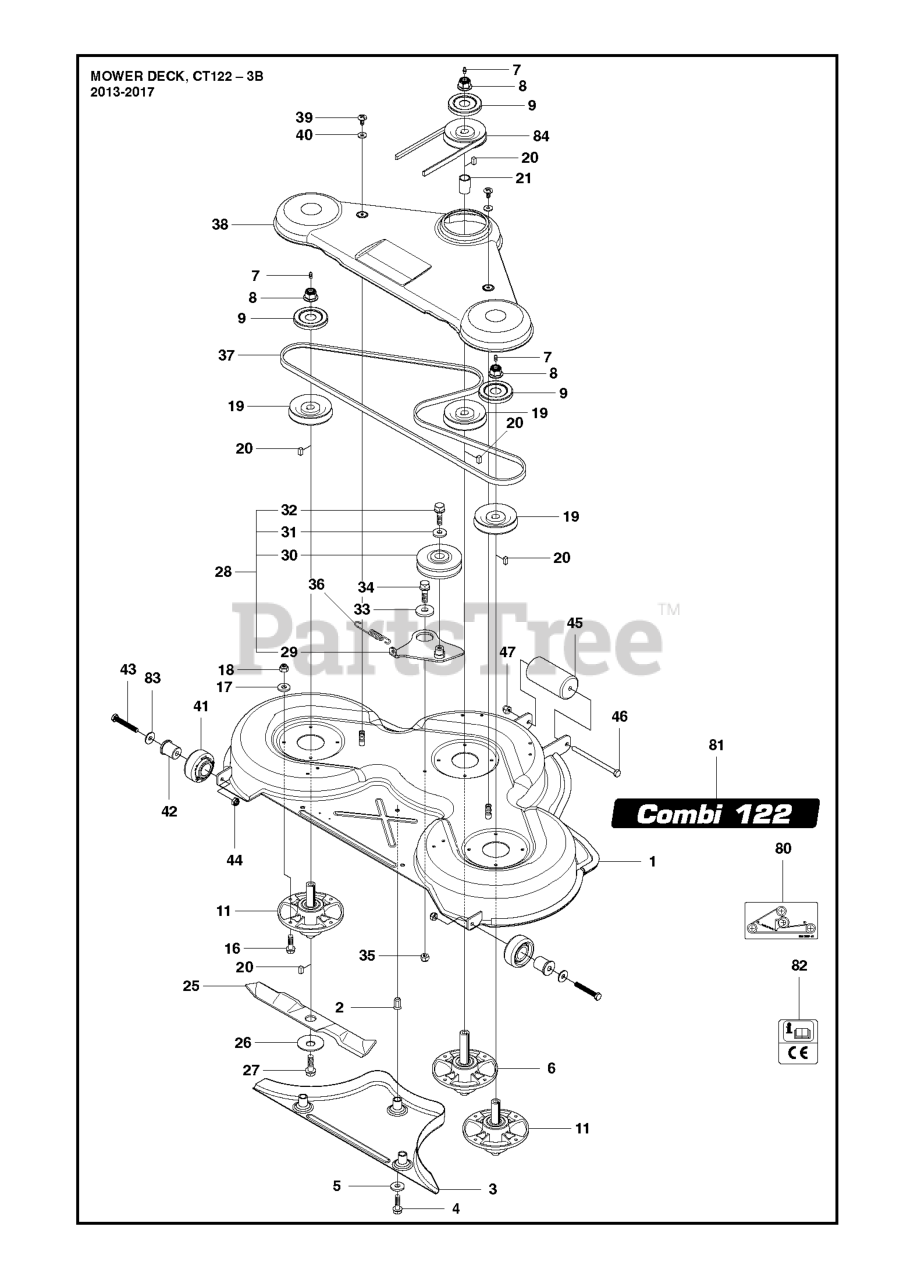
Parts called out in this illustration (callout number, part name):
4	SCREW
5	WASHER BRB 8.4X17
7	GREASE NIPPLE
16	BOLT
17	WASHER BRB 8.4X17
18	LOCKNUT M8
28	BELT TENSIONER ASSY
29	BELT TENSIONING ARM
33	WASHER
35	LOCKNUT M8
45	ROLLER
